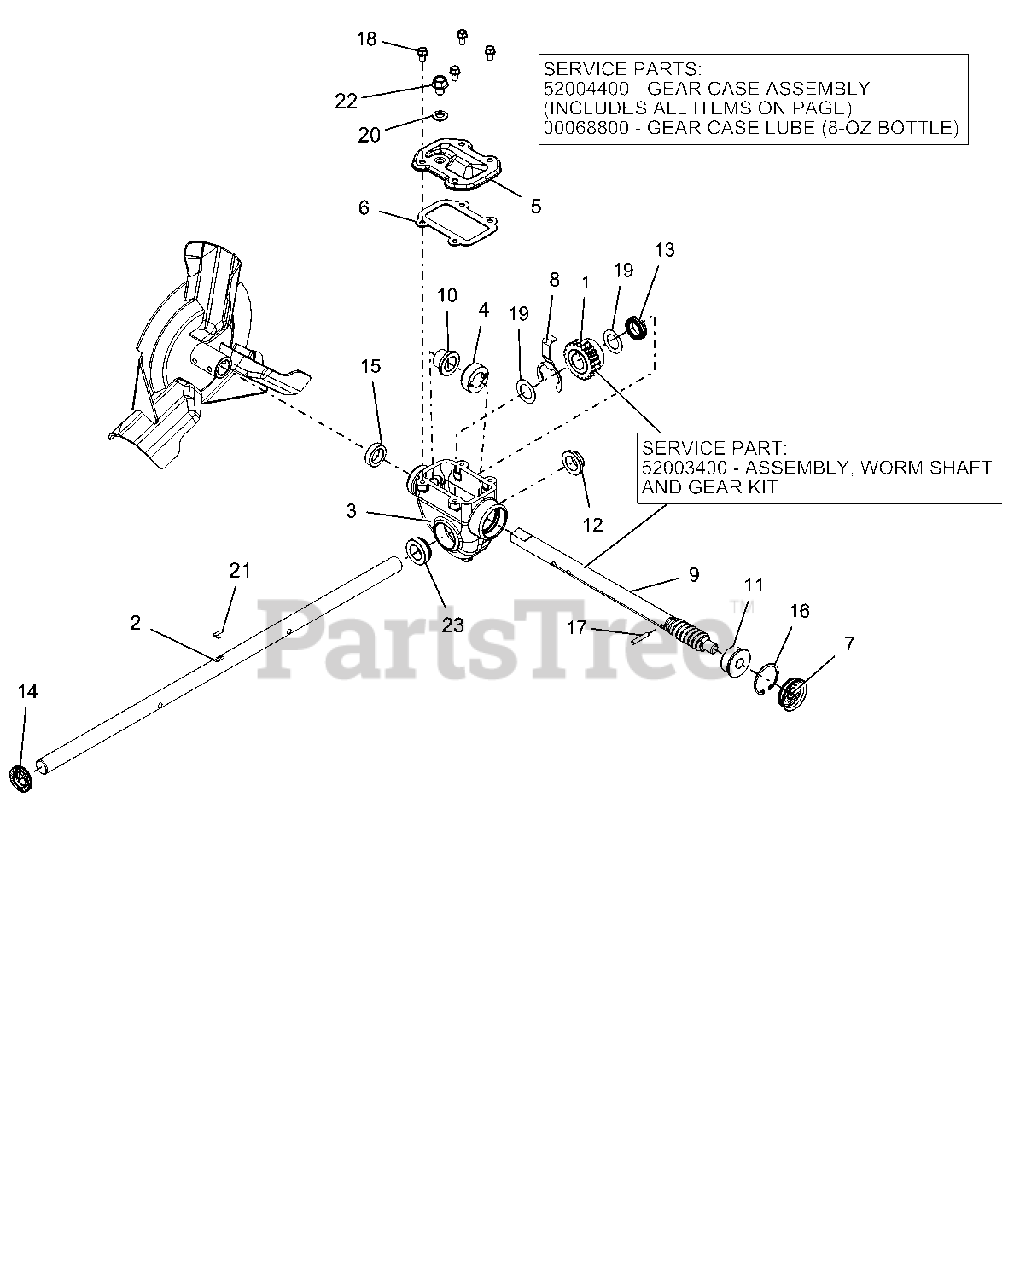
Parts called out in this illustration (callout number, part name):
1	WORM GEAR
2	SHAFT, RAKE - 24" (.750 DIA)
3	GEARCASE, COMPACT MACHINED
4	THRUST COLLAR, .75" ID SLIPFIT
5	COVER, TOP - COMPACT
6	GASKET, TOP - COMPACT GEARCASE
7	COVER, GEAR CASE 1.50"
8	BUSHING RETAINER, COMPACT
9	SHAFT, WORM - COMPACT
10	BSHG-FLG .755X.878X.75X1.25
11	BSHG-FLG .503X1.303X.62X1.465
12	BSHG-FLG .755X.878X.424X1.25
13	SEAL-OIL .748X1.125X.312 TBC29
14	SEAL-OIL .748X1.300X.250 TBC29
15	SEAL-OIL .748X1.125X.312 TB2-H
16	RG-RTNG-INT 1.500X.050
17	PIN-STR .188X1.00 6150
18	BOLT, SEMS .25-20X.50 GR5 YWZC
19	WSHR-FL-STL .760X1.225X.032 YZ
20	WSHR-BND-SEAL .38X.75X.11 GALV
21	KEY-WDRF .19X.63 HRD #61
22	@SCR-ROLOK .38-16X.50 HWH YWZC
23	BSHG-FLG COMPACT, RIGHT
24	GEAR CASE, 24" IRON SM TOP-LD
25	ARIENS L3 LUBE, 8 OZ BOTTLE
26	SHAFT AND WORM GEAR ASSEMBLY
